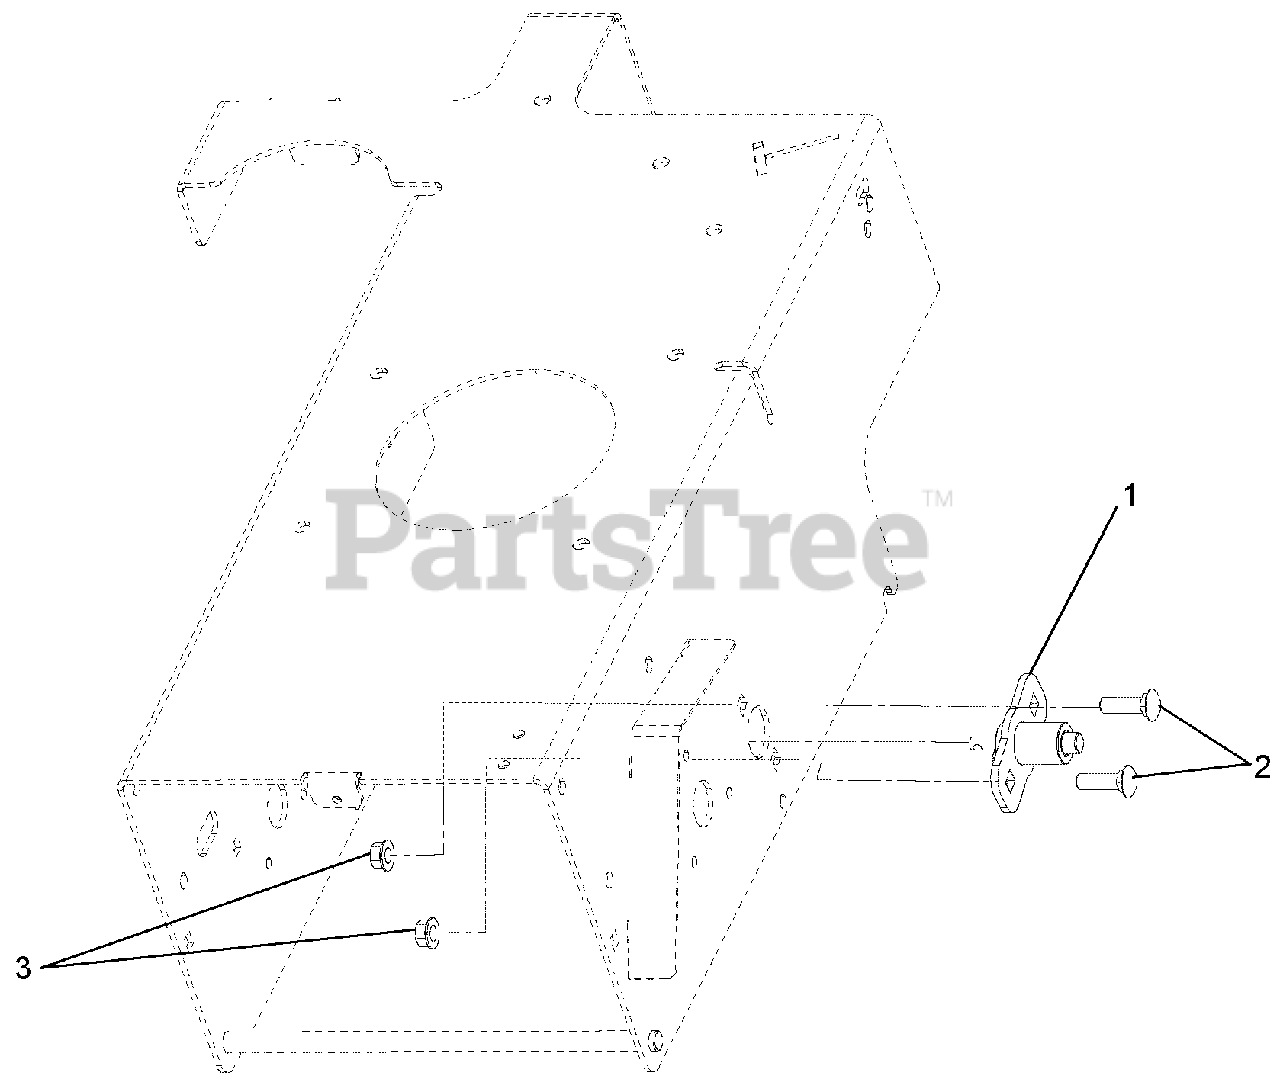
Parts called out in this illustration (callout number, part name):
1	KIT, WAW PIN BRAKE
2	@BLT-RDHDSQNK .38-16X1.25 G5YZ
3	@NUT-SPNLK-FLG .375-16 YWZC
